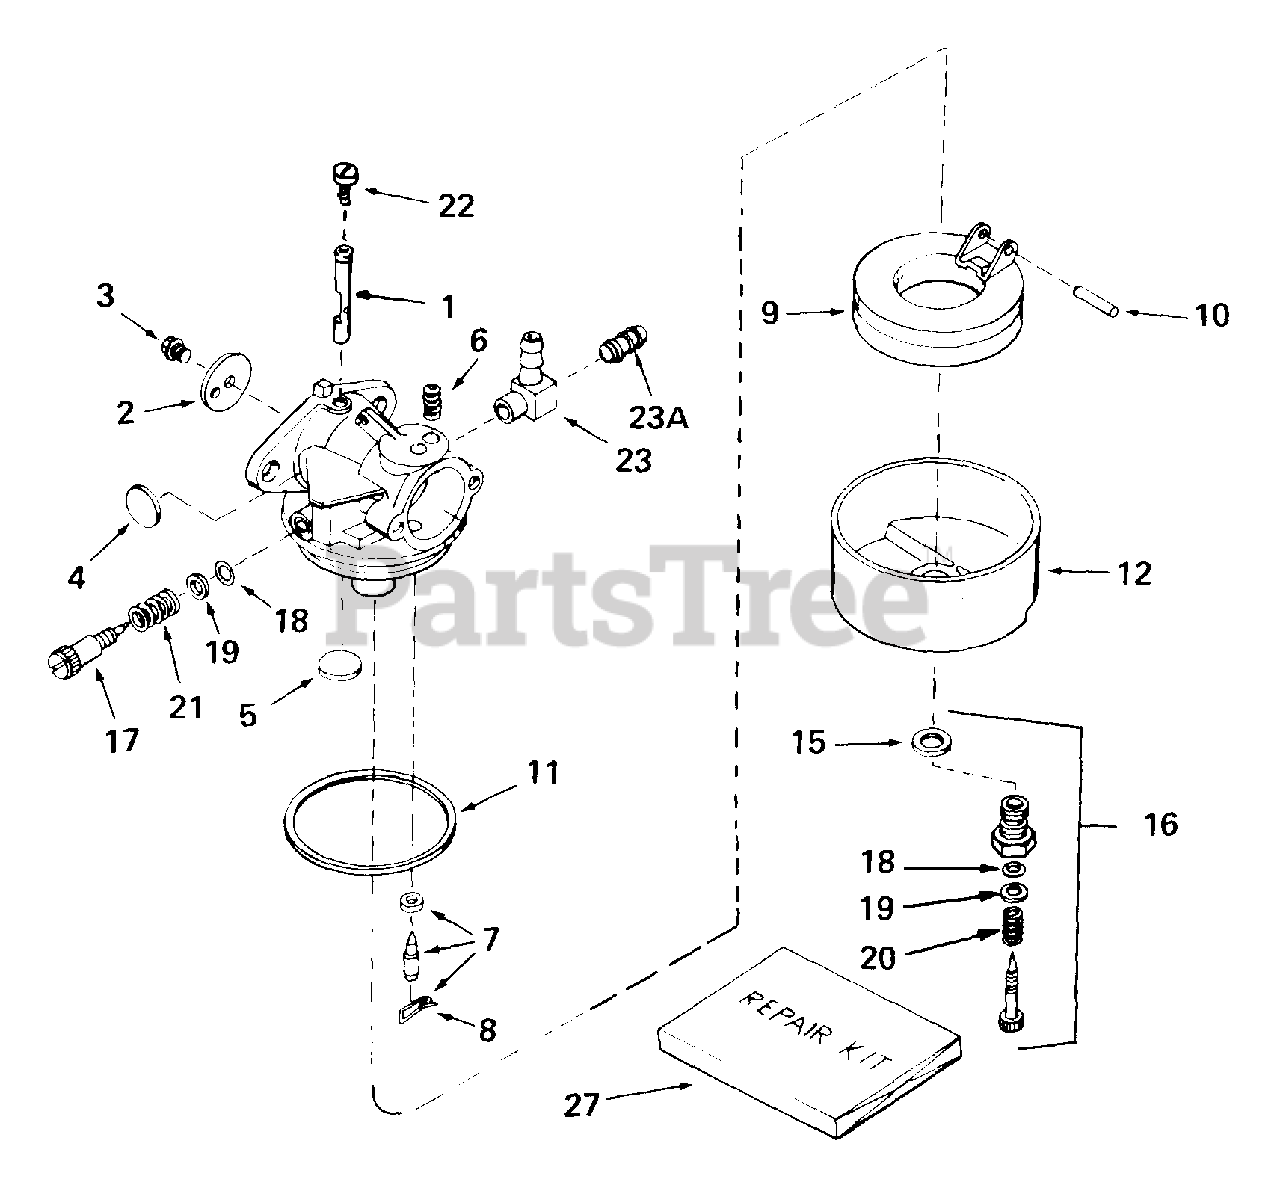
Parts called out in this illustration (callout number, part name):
1	"Shaft, Throttle
2	Shutter, Throttle
3	Screw, Throttle shutter
4	Plug, Welch
5	Plug, Welch
6	Spring, Choke positioning
7	Inlet Needle, Seat & Clip
8	Clip, Inlet Needle
9	Float, Carburetor
10	Shaft, Float
11	Gasket, Bowl-to-body
12	Bowl, Float
15	Gasket, Bowl-to body
16	Adjustment Screw Assy., Main
17	Screw, Idle adjustment
18	"O" Ring, Adjustment screw
20	Spring, Adjustment screw
21	Spring, Adjustment screw
23	Fitting, Fuel inlet
23A	Fitting, Fuel inlet
27	Repair Kit
